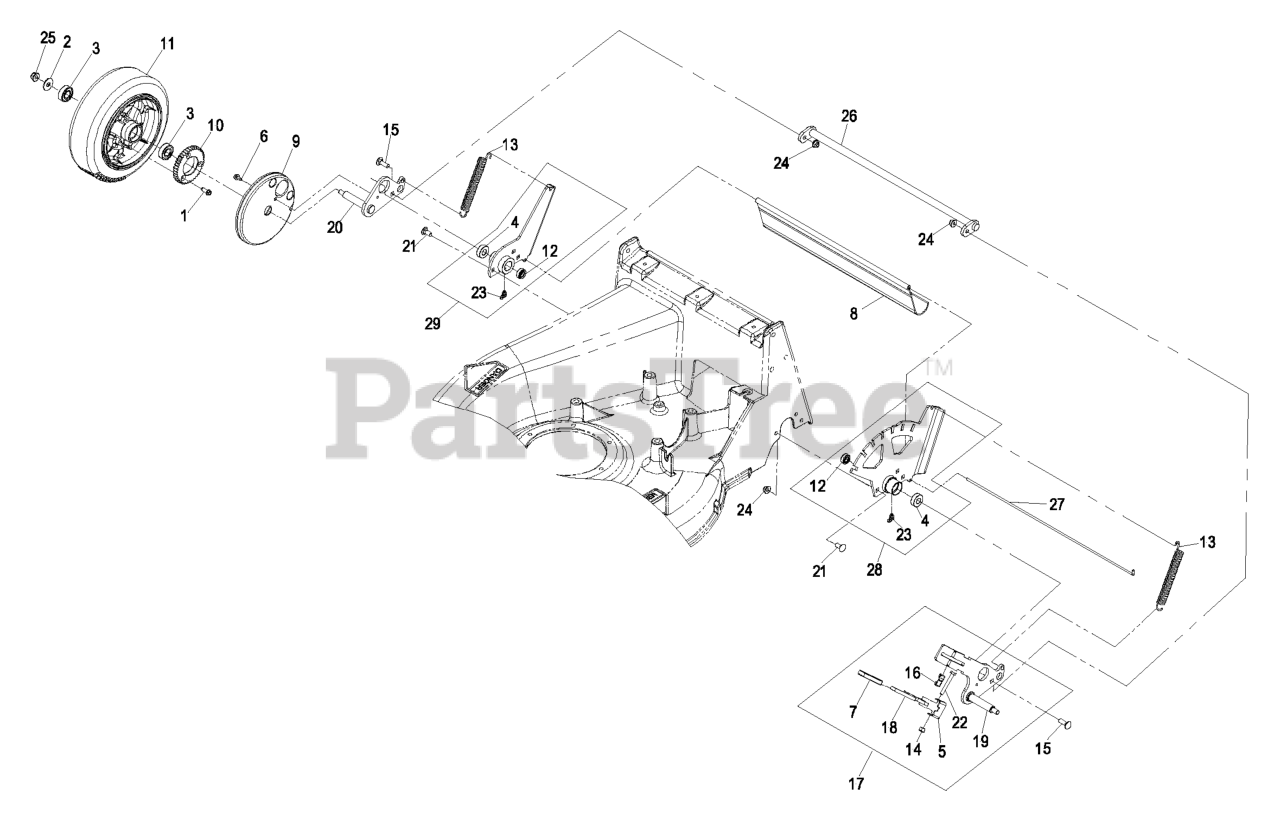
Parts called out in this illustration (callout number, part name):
1	SCREW-HWHTF
3	BEARING-BALL
4	BEARING-AXLE, REAR
5	BRACKET-PIVOT, LIFT
7	COVER-HANDLE
9	COVER-GEAR
10	GEAR-DRIVEN
11	ASM,10" TIRE AND WHEEL
12	SEAL-AXLE
13	SPRING-ASSIST, LIFT
14	NUT-LOCK, NI
15	BOLT-CARR
16	SPRING-LATCH
17	ASM,REAR ADJUSTER
18	LEVER-LIFT
19	ARM-AXLE, LH
20	ARM-AXLE, RH
21	BOLT-CARR
22	SCREW-HH
23	FITTING-GREASE
24	NUT-HF, NI
25	NUT-HF, NI
26	ROD-TORQUE
27	ROD-SHIELD
28	LH BEARING SUPPORT ASM
29	RH BEARING SUPPORT ASM
